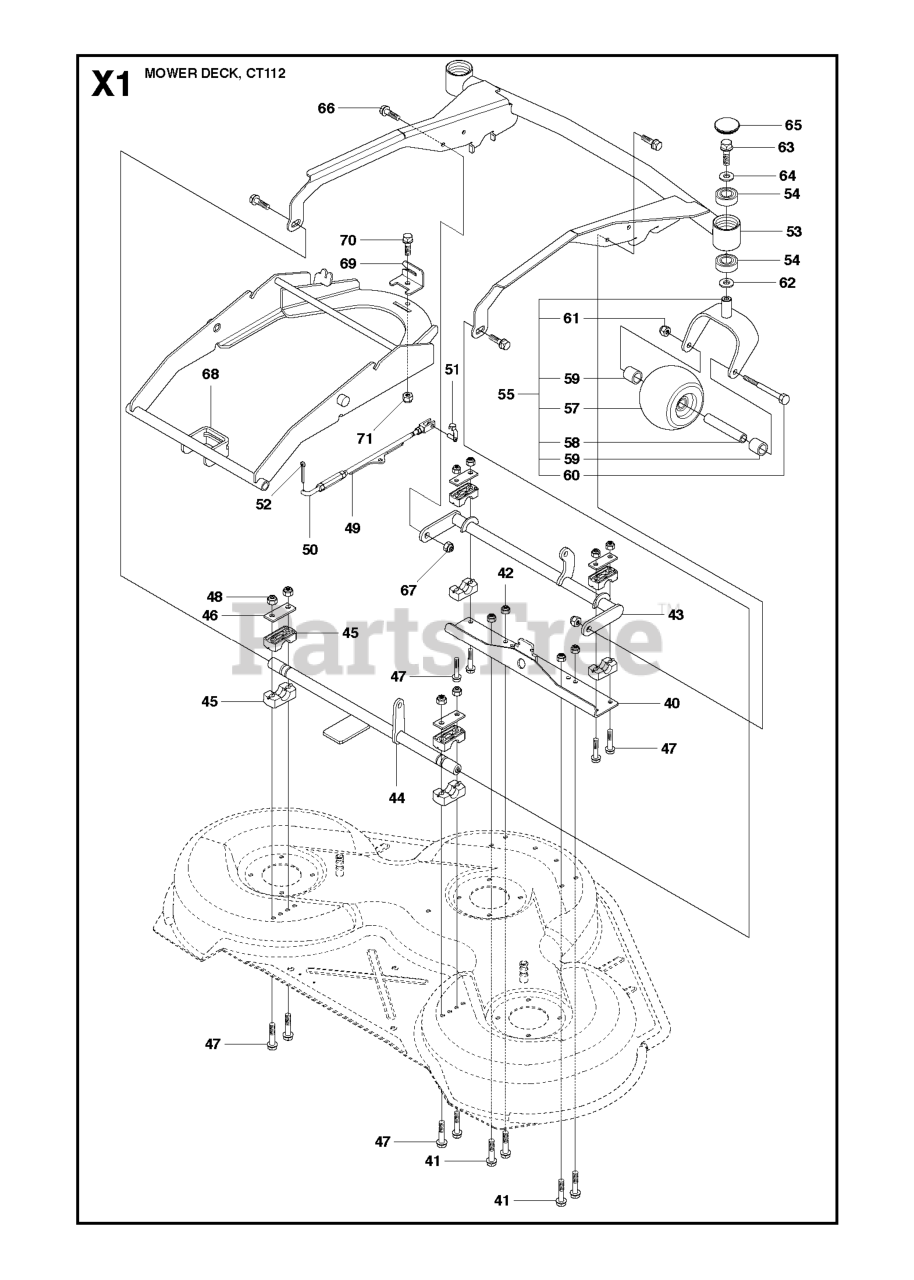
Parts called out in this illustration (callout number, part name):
42	LOCKNUT M8
48	LOCKNUT M8
50	PARALLEL ROD
54	BALL BEARING 6004-2RS1
55	PIVOT WHEELS
57	DECK ROLLER, FRONT
61	NUT
65	HUB CAP PIVOT WHEEL
67	LOCKNUT M8
71	LOCKNUT M8
